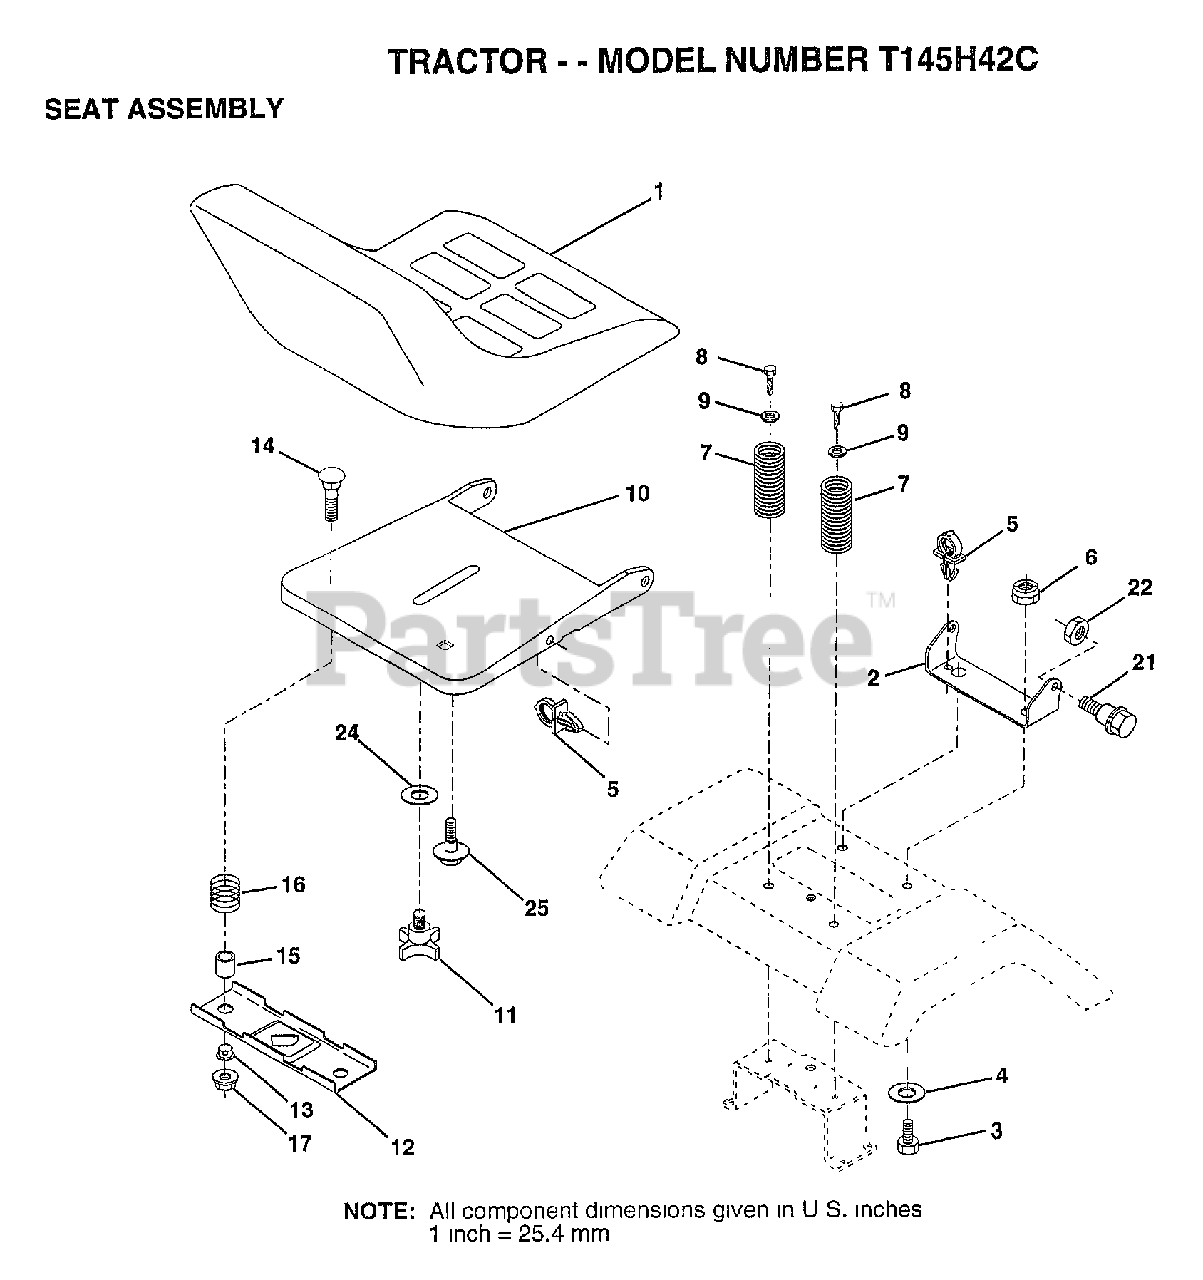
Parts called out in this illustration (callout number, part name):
2	BRACKET PVT SEAT
3	BOLT
4	WASHER PM
5	CLIP.PUSH-IN.HING
6	NUT
7	SPRING COMPRESSIO
8	SCREW GTV
9	WASHER
10	PAN-SEAT
11	"KNOB 1/2"" YT"
12	BRKT SWITCH
13	BUSHING
14	BOLT-RD HD SQ NK
15	SPACER SPLIT
16	SPRING COMPRESSED
21	"BOLT,SHOULDER"
22	NUT
24	WASHER
25	"BOLT,SHOULDER"
